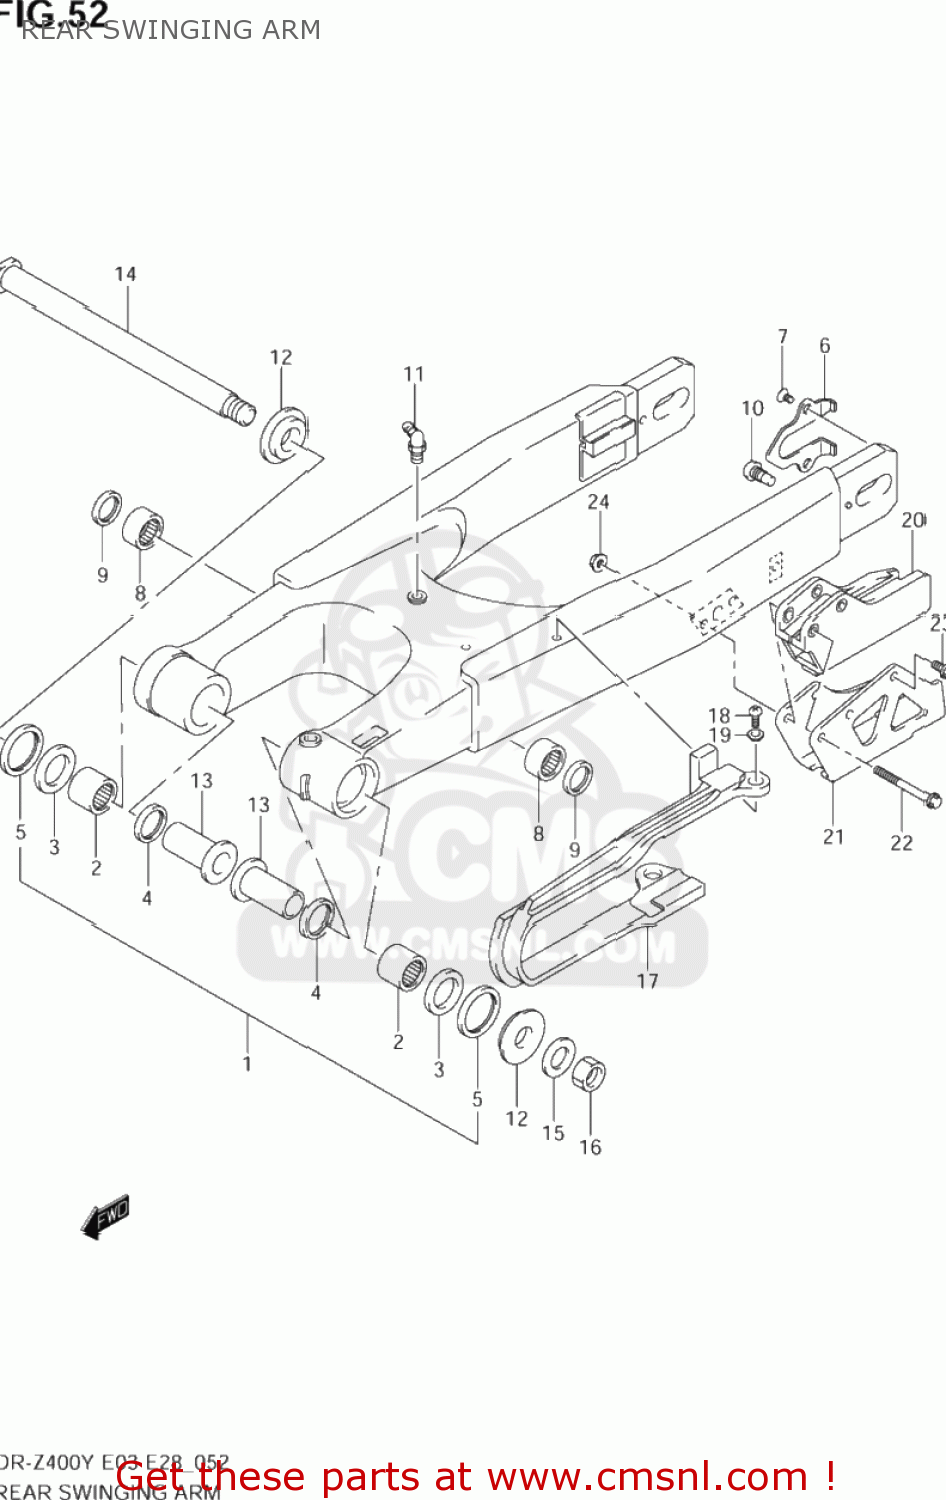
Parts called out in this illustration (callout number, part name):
1	SWING ARM ASSEMBLY,REAR
2	BEARING(22X29X30)
3	BEARING(22X35X2)
4	SEAL,OIL(22X29X4)
5	SEAL,RR SWGARM PIVOT OUTER
6	PLATE,RR SWING ARM AXLE
7	SCREW(5X8)
8	BEARING(20X27X15)
9	SEAL,CUSHION LEVER DUST
10	STOPPER,CHAIN ADJUSTER
11	NIPPLE,GREASE
12	SPACER,SWINGINGARM PIVOT OUTER
13	SPACER,SWGARM PIVOT INNER
14	SHAFT,RR SWINGINGARM PIVOT
15	WASHER, FIXED DRIVE FACE
16	NUT
17	BUFFER,CHAIN TOUCH DEFENSE
18	SCREW
19	WASHER
20	GUIDE,CHAIN
21	PLATE,CHAIN GUIDE
22	BOLT
23	BOLT
24	NUT
